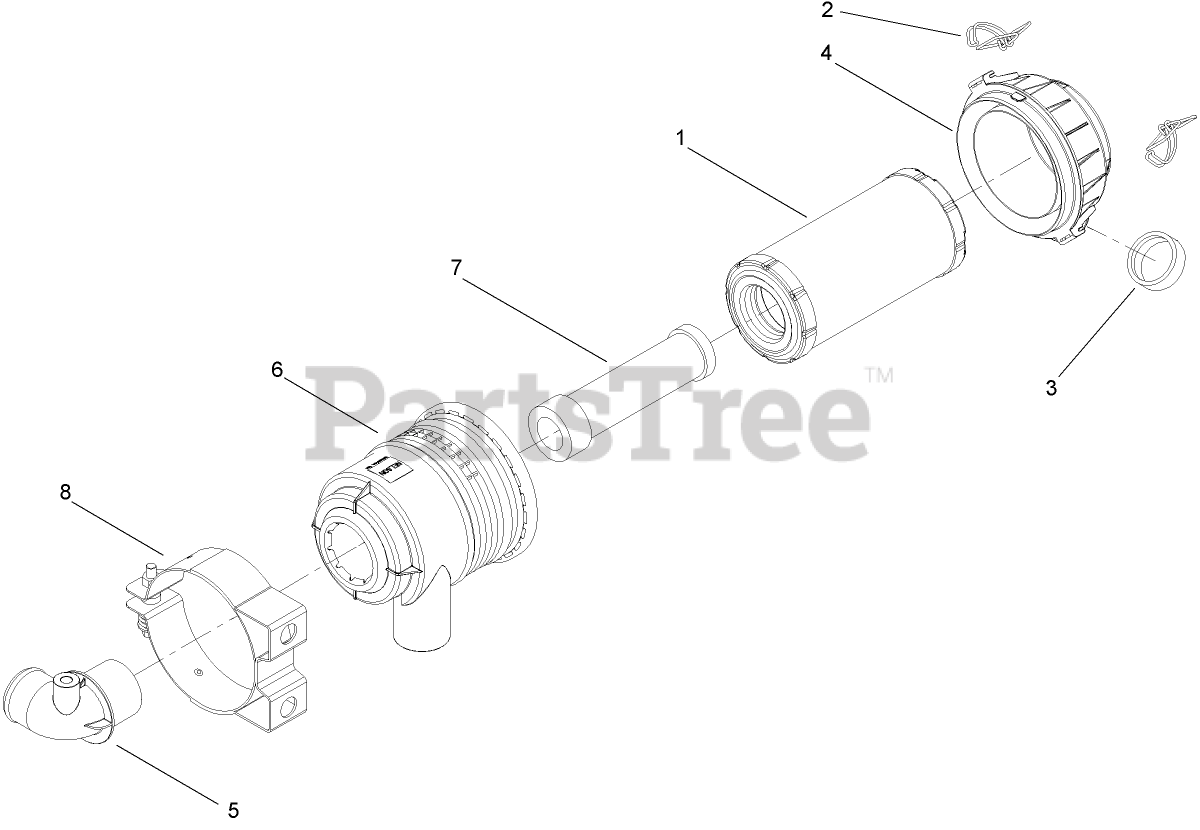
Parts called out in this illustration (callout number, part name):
1	ELEMENT-FILTER, AIR
2	CLIP-CLEANER, AIR
3	VALVE-EJECTOR, DUST
4	COVER
5	TUBE ASM
6	HOUSING
7	FILTER-SAFETY
8	MOUNTING BRACKET ASM
